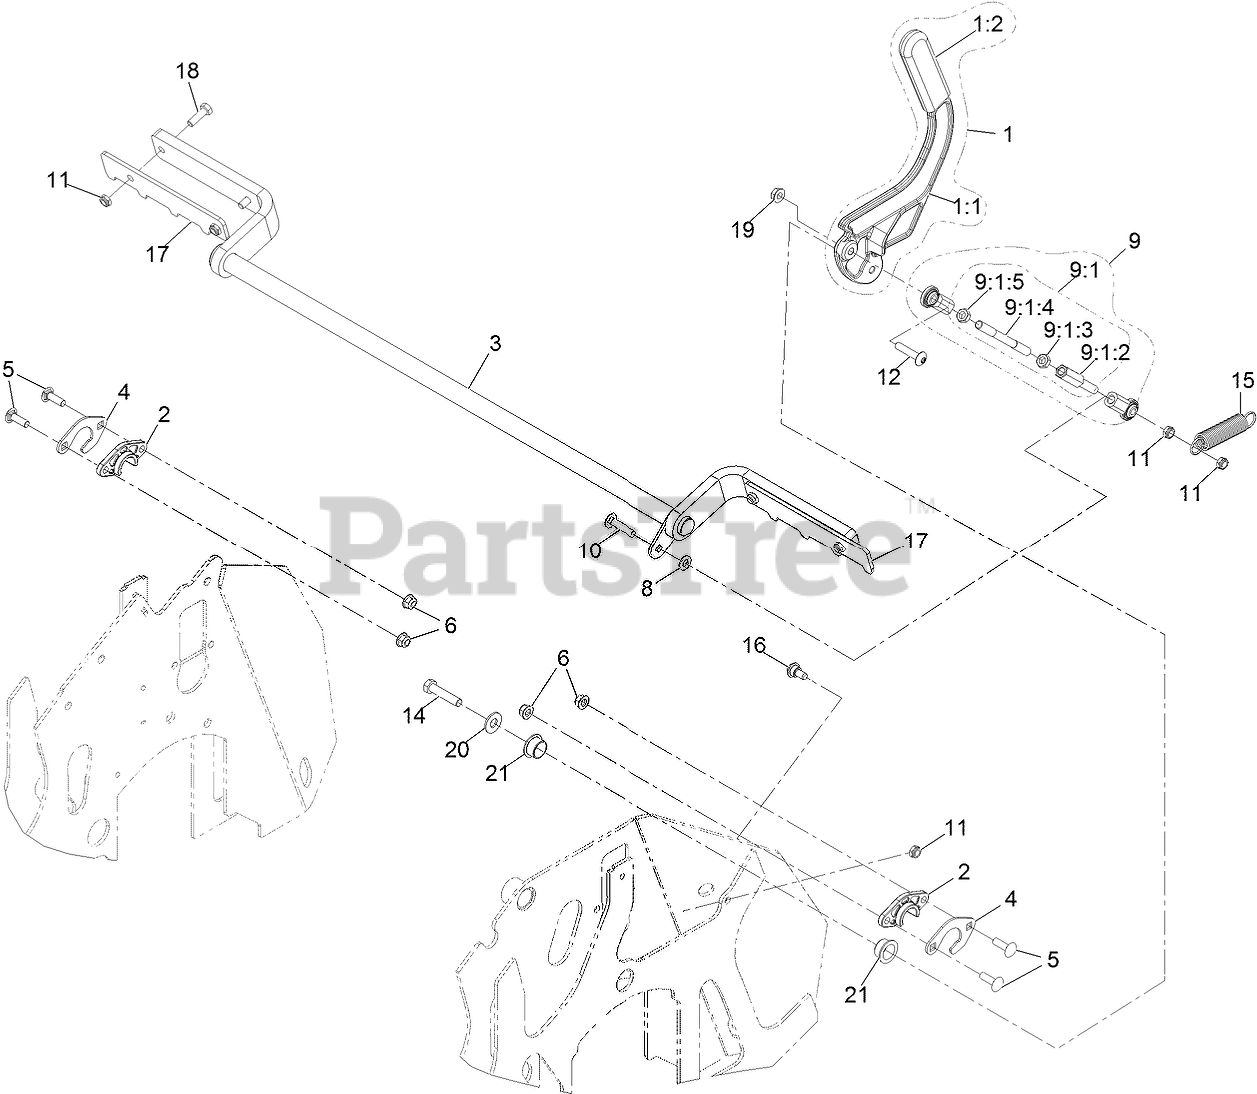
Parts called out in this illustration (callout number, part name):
1	ASM, Brake Lever W/ Grip
1:1	Weld, Brake Lever
1:2	GRIP-LEVER
2	BUSHING-FLANGE
3	Weld, Brake Shaft
4	Support, Bearing
5	SCREW-CARR
6	NUT-HF, NI
8	WASHER-PLAIN
9	ASM, Linkage
9:1	ASM, Motion Control Link
9:1:2	ROD-ADJUSTMENT
9:1:3	NUT-HEX JAM, LH
9:1:4	Link, Motion Control
9:1:5	NUT-HJ
10	BOLT-CARR
11	NUT-LOCK, NI
12	SCREW-TORX
14	SCREW-HH
15	SPRING-IDLER
16	BOLT-SHOULDER
17	Plate, Snubber
18	SCREW-HH
20	WASHER-FLAT
21	Bushing, Igus
